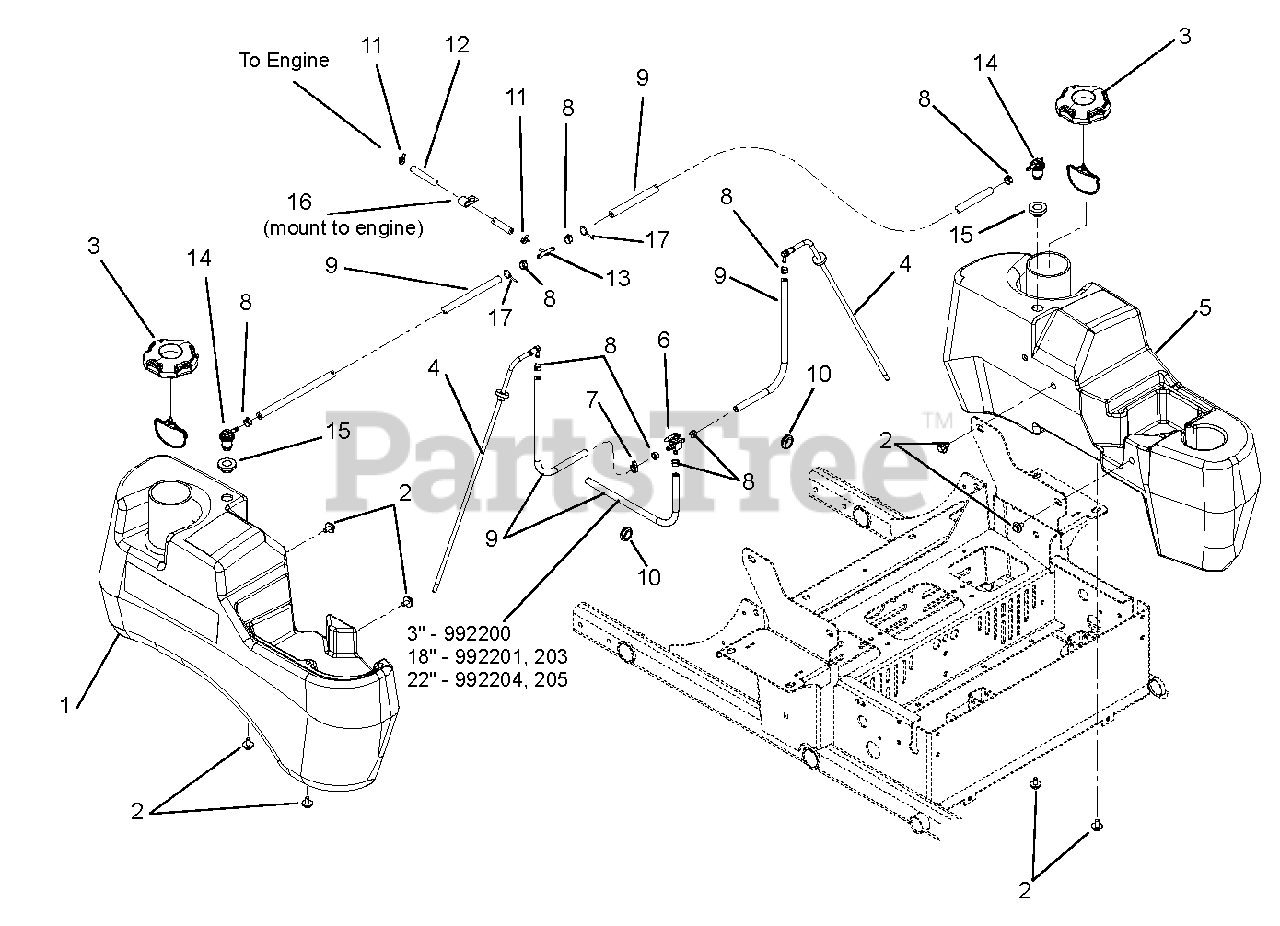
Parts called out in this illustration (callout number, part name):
1	Tank, Right Hand Fuel
2	Bolt, SEMS .31-18 x .62
3	Cap, Fuel, Vent-In Autolock
4	Assembly, Large Tank Fuel Pick-Up
5	Tank, Left Hand Fuel
6	Valve, Fuel
7	Routing Clip (1/2" ID)
8	Clamp, Fuel Line
9	Hose, .25 Low-Perm Bulk Gas
10	Grommet, Rubber 5/8 ID/1.13 OD
11	Clamp, Hose, Spring .188
12	Hose, .188 Low-Perm Bulk Gas
13	Tee, 1/4HS Run x 3/16HS Branch
14	Valve, Combination
15	Grommet, Remote Vent Nitrile
17	Cable Tie with Tree (.25 hole)
